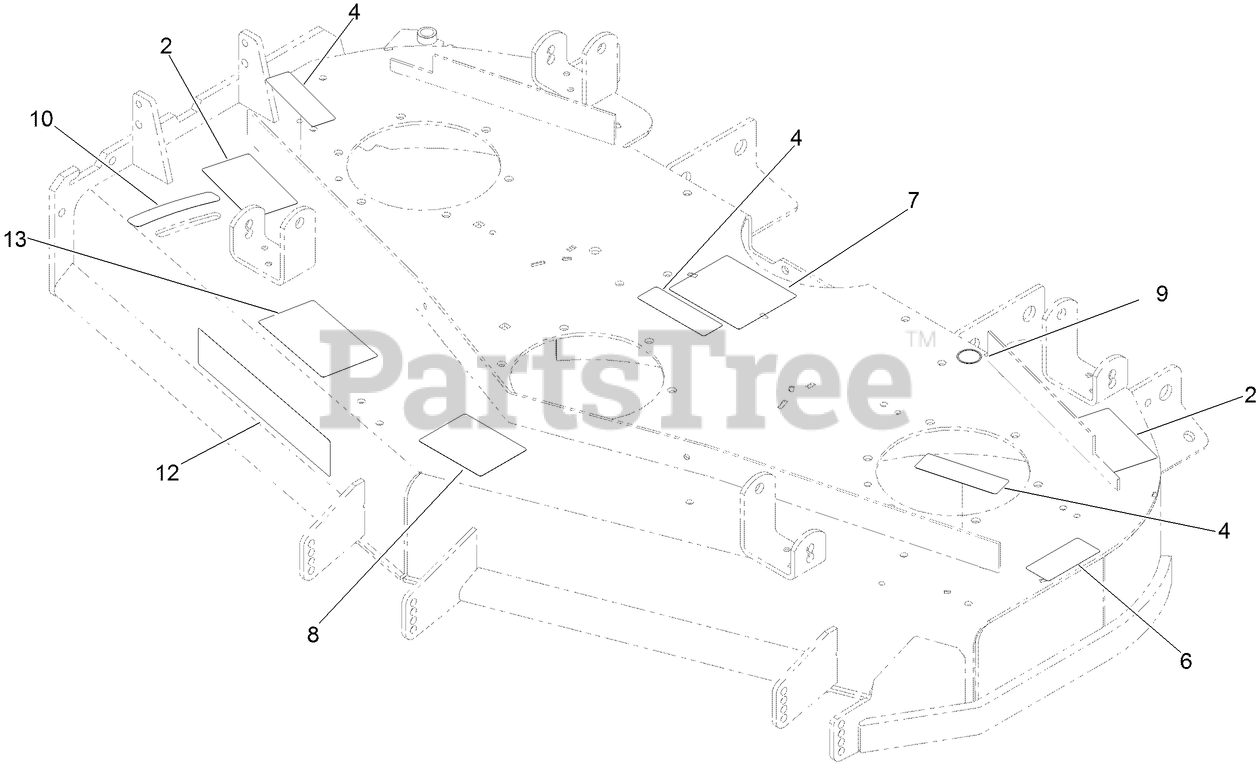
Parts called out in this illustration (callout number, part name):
2	DECAL-DANGER
4	DECAL-COVER, MISSING
6	DECAL-BOLT TORQUE
7	DECAL-ROUTING, BELT
8	DECAL-SCALP, ANTI
9	DECAL-GREASE
10	DECAL-SETTING, BAFFLE
13	DECAL-ADJUSTMENT, BAFFLE
